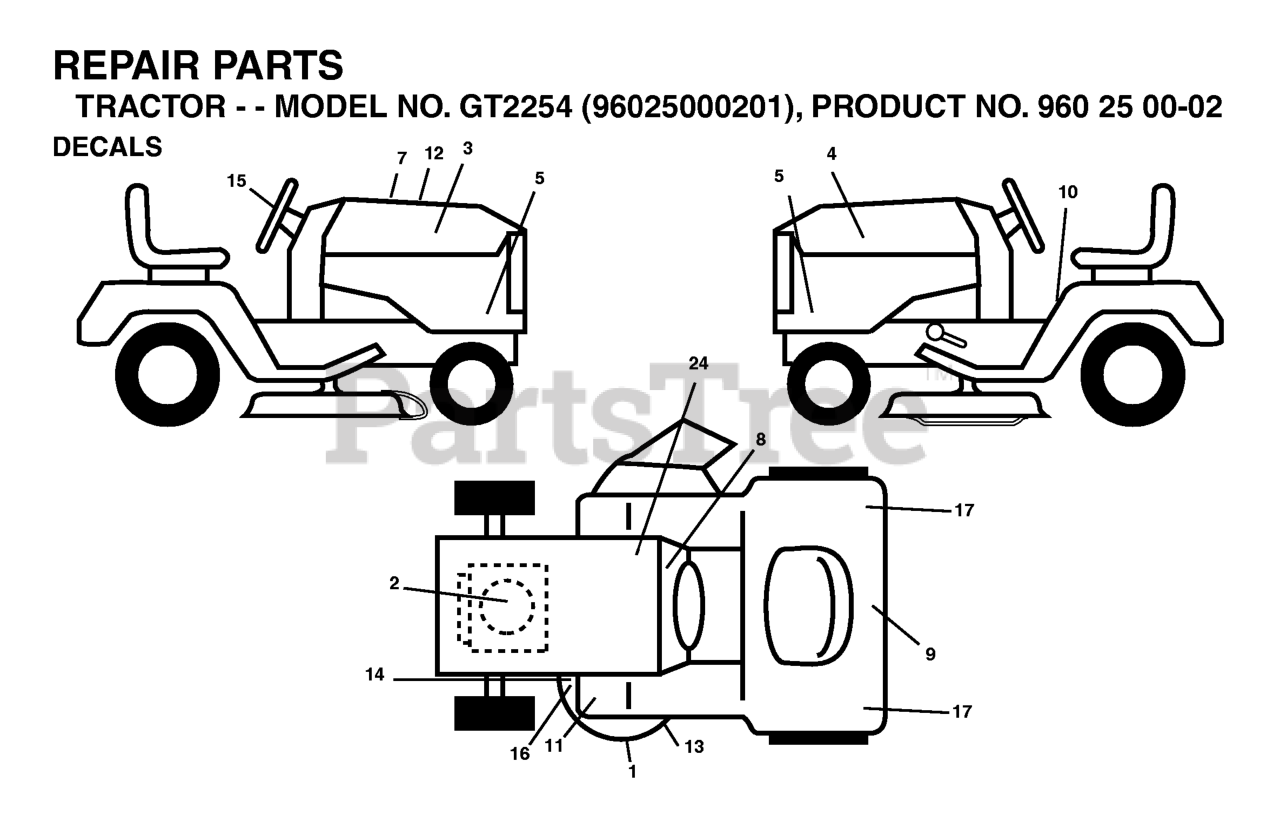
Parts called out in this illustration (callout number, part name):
2	DECAL.ENGINE
5	DECAL.PANEL
7	DECAL HOOD CUST. RESP.
8	DECAL.DASH.GEAR.AMM.LOWES
9	DECAL.FENDER
13	DECAL.SCHEMATIC.DECK
14	DECAL.MOWER
15	DECAL.STEERING.HUSQ.BLUE
16	DECAL.MOWER
17	REFLECTOR-TAIL YT
24	DECAL BTRY SYMBOLS
